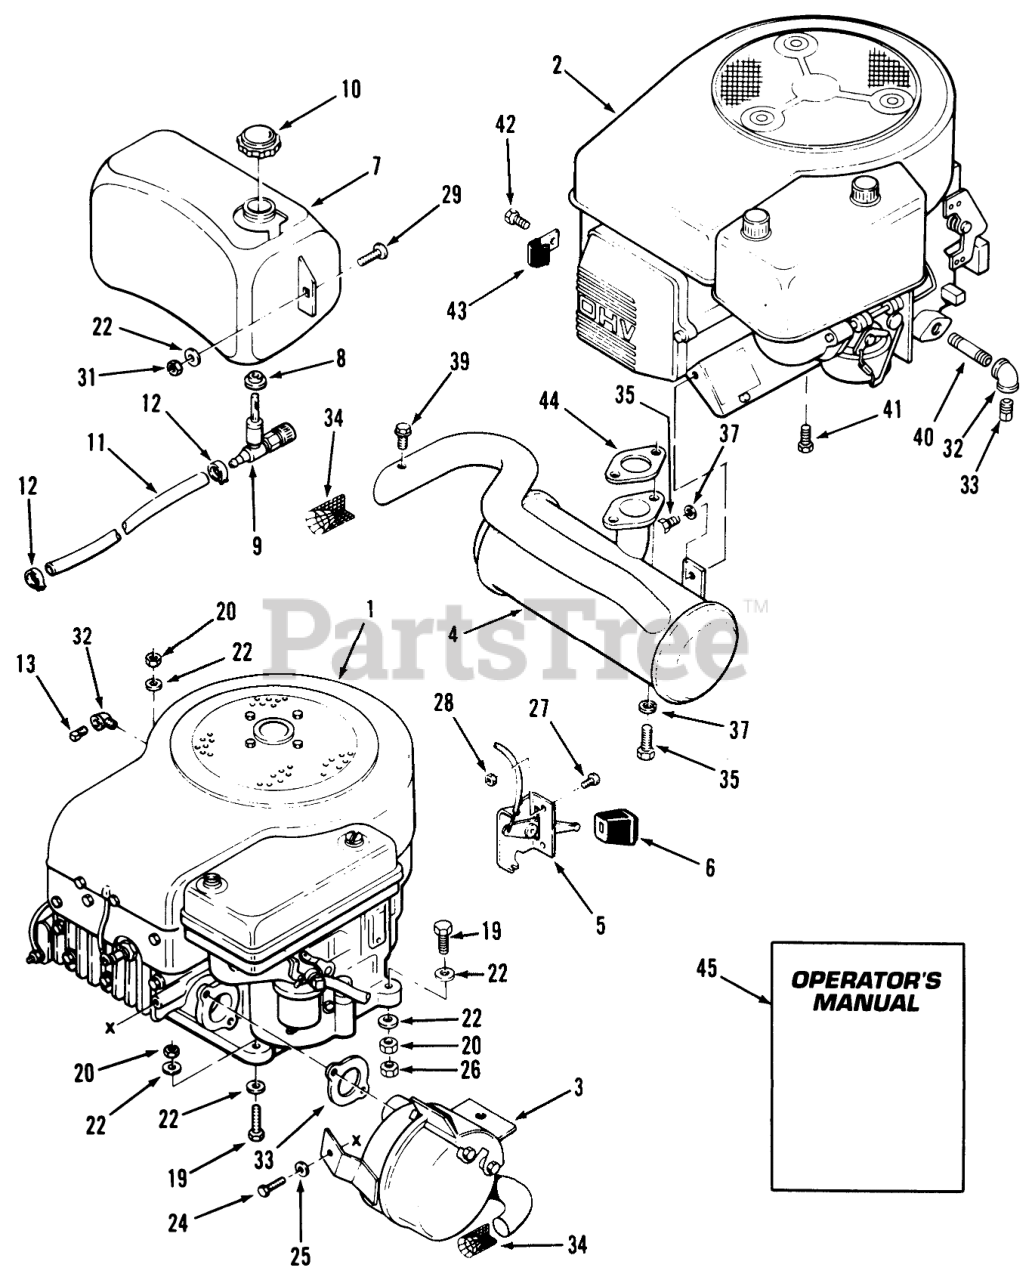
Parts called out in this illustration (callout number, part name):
2	Engine-12 HP-TORO POWER PLUS Model E125V-N/10964B
3	MUFFLER
4	MUFFLER-EXHAUST
5	THROTTLE-CONTROL
6	KNOB-CONTROL
7	Fuel Tank Assembly (Incl. Ret. #8 & 9)
8	BUSHING
9	VALVE-FUEL
10	CAP GAS
11	FUEL LINE 19" OF 6554
12	CLAMP-HOSE
13	Plug
19	HHCS
20	Nut
22	WASHER-PLAIN
24	Bolt
26	Nut
27	Screw
28	Nut
29	BOLT-CARR
31	NUT-LOCK, NI
32	STREET ELBOW 45DEGRE
33	Plug-Pipe
34	Arrester-Spark
35	HHCS M8X1.25X20
37	WASHER-LOCK
39	BOLT-HEX S.T. #8X1/2
40	Pipe
41	Bolt
42	SCREW
43	J-CLIP
44	GASKET-EXHAUST
45	Manual-Engine (210-5 & 210-H)
